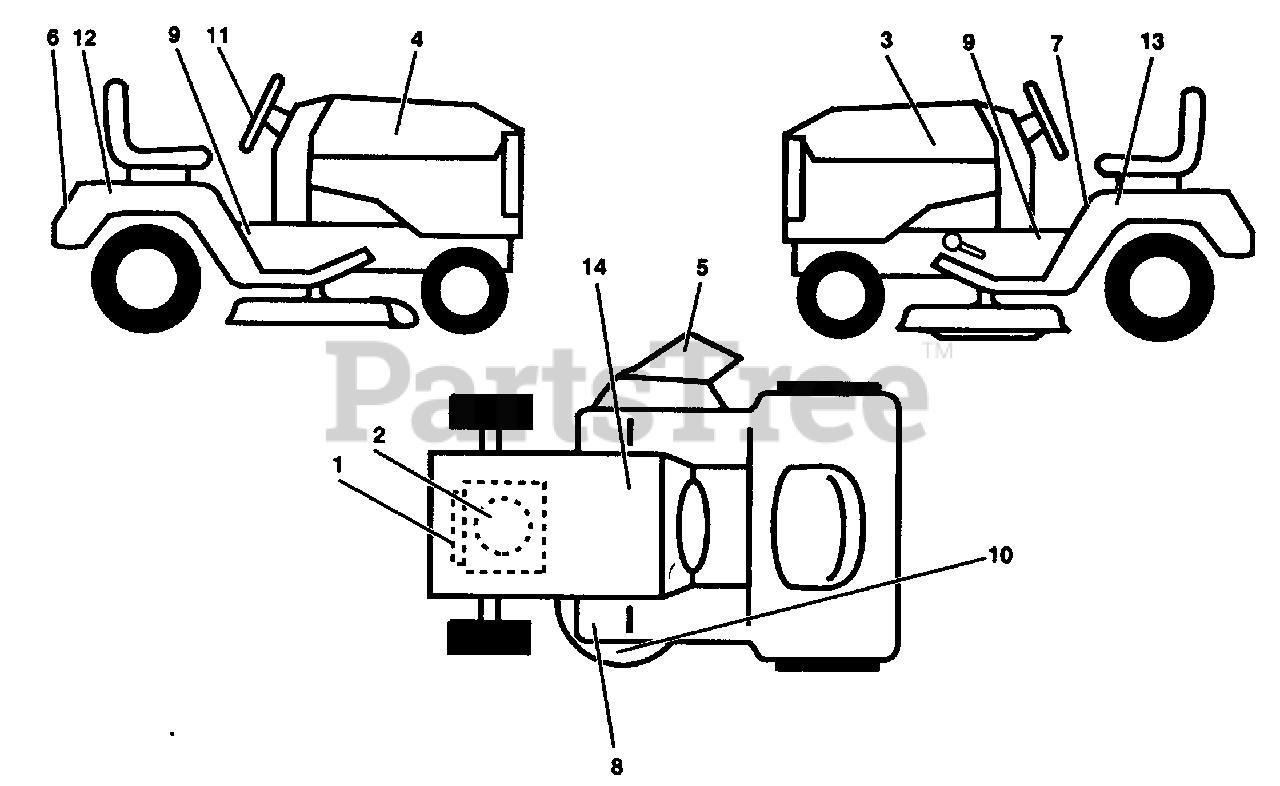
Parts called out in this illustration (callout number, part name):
1	Decal, Instruction Engine (AYP part number)
2	Decal, Engine (AYP part number)
3	Decal, Hood Stripe L.H. (AYP part number)
4	Decal, Hood Stripe R.H. (AYP part number)
5	Decal, Danger, Deflector (English/French) (AYP part number)
6	Decal, Fender/Grill (AYP part number)
7	Decal, Caution (English/French) (AYP part number)
8	Decal, Clutch/Brake (English/French) (AYP part number)
9	Decal, Chassis (AYP part number)
10	Decal, Rotating Blades (AYP part number)
11	Decal, Steering Wheel Insert Manual Owner's (AYP part number)
12	Decal, Fender, R.H., 6 Sp. (AYP part number)
13	Decal, Fender, L.H., 6 Sp. (AYP part number)
14	Decal, Caution, Battery (French/German) (AYP part number)
